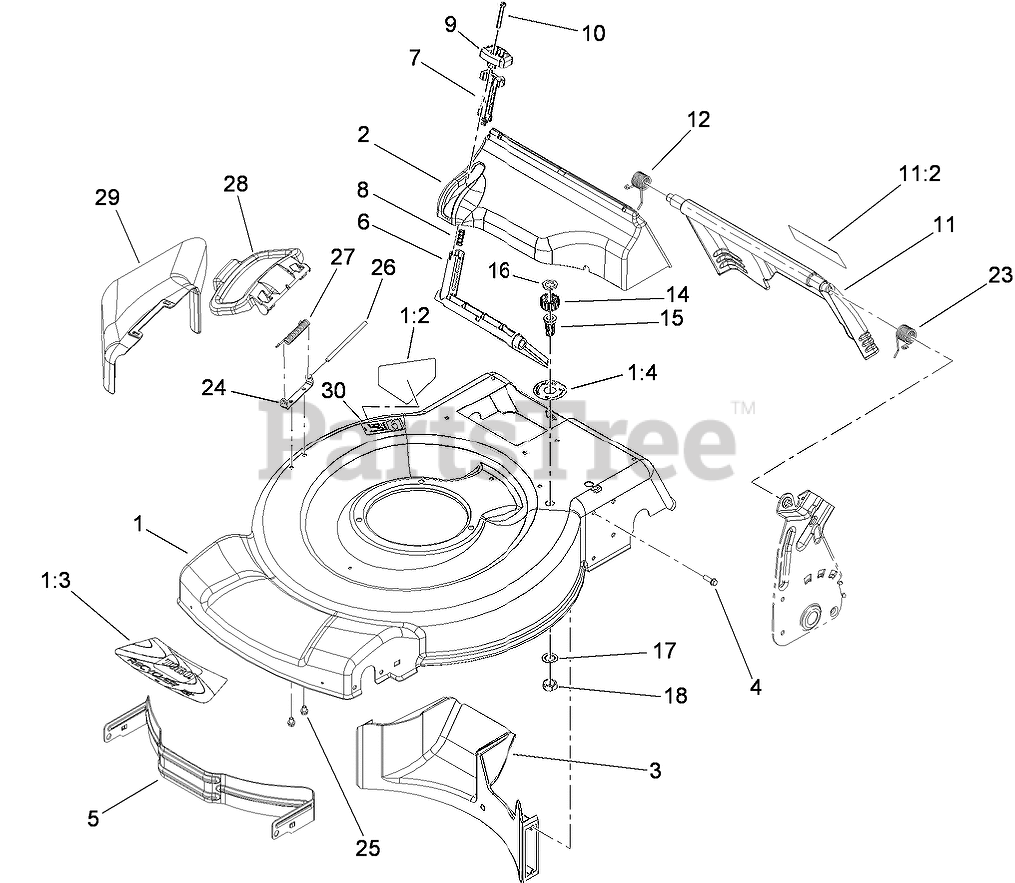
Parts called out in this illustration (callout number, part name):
1	HOUSING ASM
1:2	DECAL-DANGER
1:3	DECAL-RECYCLER
1:4	DECAL-PORT, WASHOUT
2	CHUTE-RECYCLE
3	BAFFLE-REAR
4	SCREW-HWH
5	BAFFLE-FRONT
6	DEFLECTOR-RECYCLE
7	LATCH-RECYCLE
8	SPRING-COMPRESSION
9	KNOB-RECYCLE
10	SCREW-PPH
11	REAR DOOR ASM
11:2	DECAL-WARNING
12	SPRING-TORSION
14	COUPLING-HOSE, WASHOUT PORT
15	PORT-WASHOUT
16	WASHER-SEAL, WASHOUT PORT
17	WASHER-TOOTH, INTERNAL
18	NUT-JAM
23	SPRING-TORSION
24	BRACKET-COVER
25	SCREW-HWH
26	ROD-COVER
27	SPRING-TORSION
28	DEFLECTOR-SIDE
29	CHUTE-DISCHARGE, SIDE
30	DECAL-PLACEMENT, FOOT
